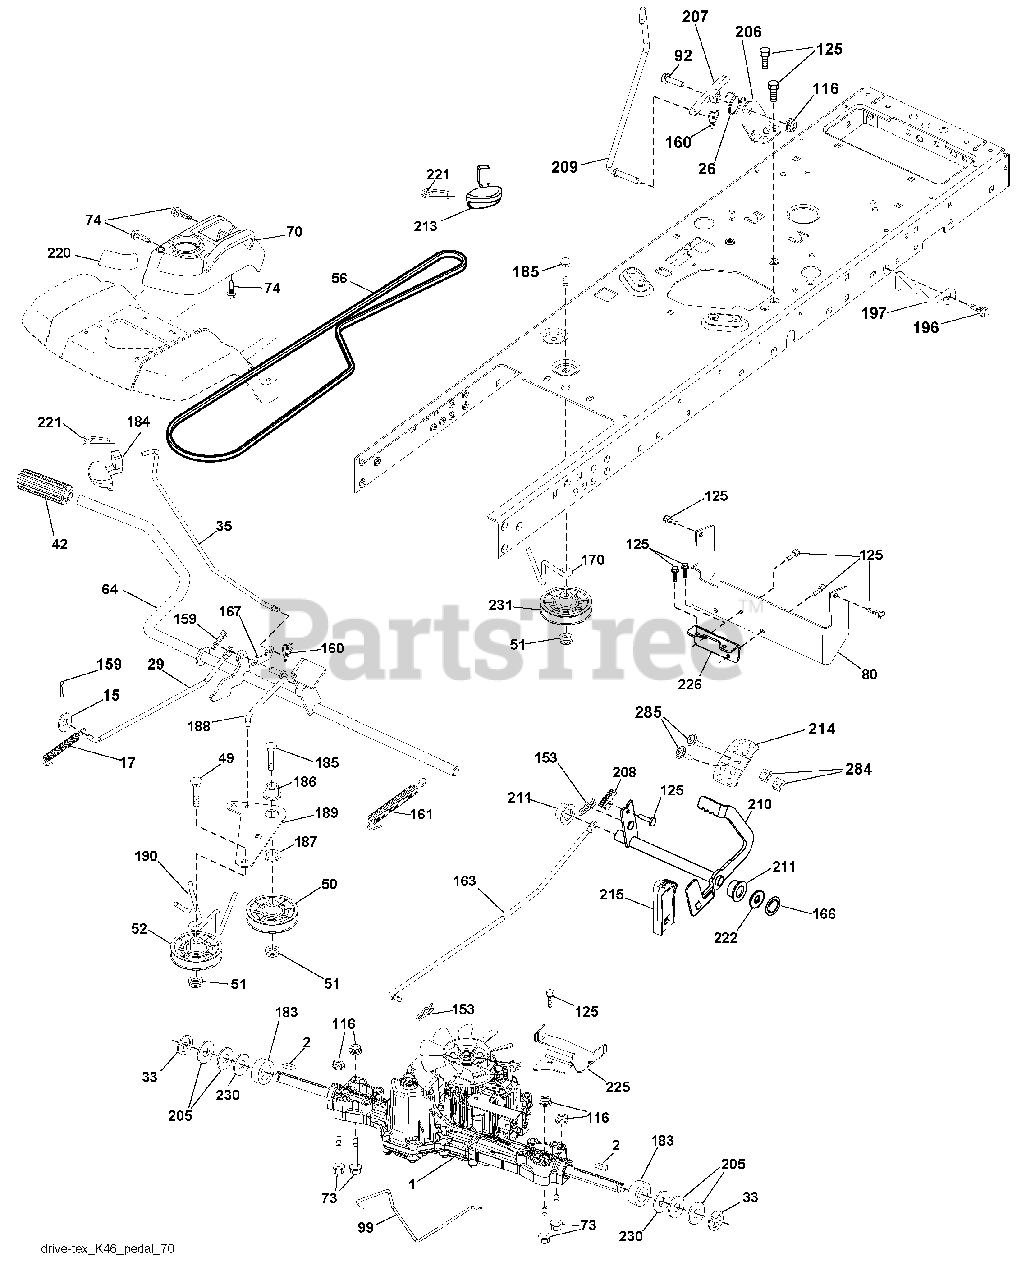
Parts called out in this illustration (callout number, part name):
15	Washer 13/32 x 13/16 x 16 Ga.
17	Spring, Brake
26	Spring Return Cruise
29	Rod, Brake
35	Rod, Brake, Park
42	Cover, Foot Pedal
50	Pulley Idler Flat
51	Lock Nut 3/8-16
52	Idler V-Groove 910" Offset
56	V-Belt, Drive
64	Shaft Asm. Pedal Brake Control
70	Console Asm Pch
73	Bolt Hex Flghd 5/16-18 Gr. 5
74	Screw Hex Wsh Hi-Lo 1/4 x 1/2
80	Bracket Strap Torque
92	Bolt Fin Hex 5/16-18 unc x 1.25
99	Rod Spring Bypass
116	Nut Lock Hex Flange 5/16-18
125	Screw 5/16-18 x 3/4
153	Retainer Spring
159	Pin Cotter 1/8 x 3/4
160	Retainer Clip
161	Spring, Return, Clutch
163	Rod Pedal Control
167	Latch Brake Parking
170	Keeper Belt Centerspan
183	Spacer Split
184	Handle Parking Brake
185	Bolt Rdhd Sqnk 3/8-16 x 2-1/2
186	Spacer Retainer
187	Washer
188	Link Clutch Ground Drive
189	Bellcrank Ground Drive
190	Keeper Bellcrank Ground Drive
196	Screw 3/8-16 x 1
197	Bracket Clutch Anti-Rotation
206	Bracket Mount Latch Cruise
207	Latch Control Cruise
208	Gear Sector Control Cruise
209	Rod Control Cruise
210	Rocker Asm. Pedal Control
211	Bearing Nylon
213	Knob Control Cruise
214	Pedal Forward Husq
215	Pedal Reverse
220	Reflector RH
221	Retainer Spring Clip Handle
222	Washer 21/32 x 1-1/4 x 10 Ga.
225	Keeper Belt Trans.
226	Bracket Mount Torque
230	Washer Hardened
231	Idler V-Groove
284	Nut U-CHNL 1/4-20 550DP .350 PNL
285	Screw PHD 1/4-20 Box Drive
